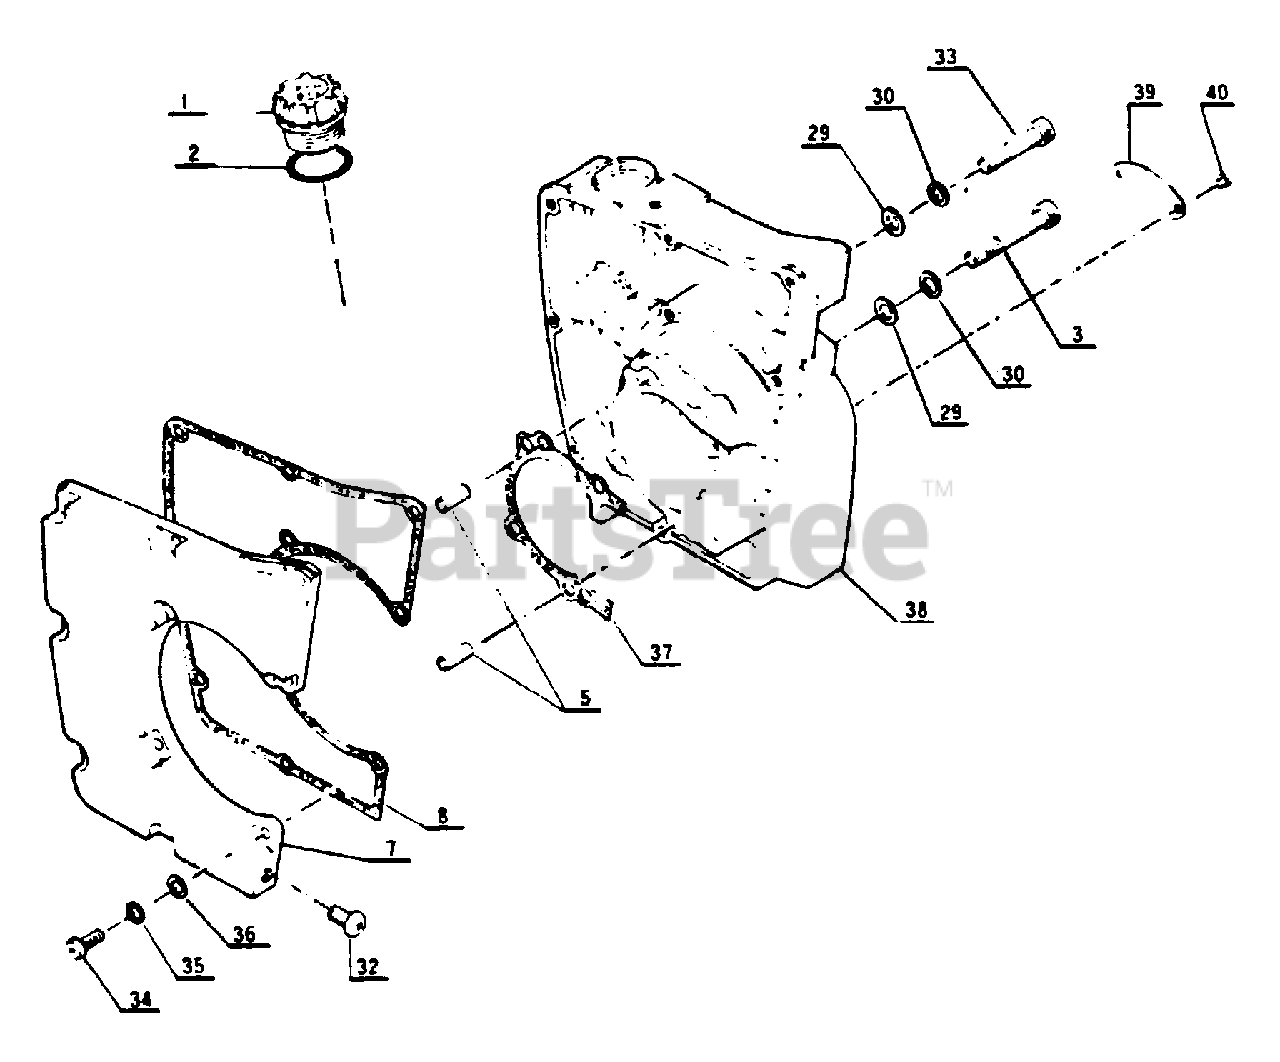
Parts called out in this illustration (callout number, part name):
1	CAP
2	GASKET, CAP
3	BOLT
5	PIN - LOCATING
7	TANK, OIL
8	GASKET
29	WASHER - 5
30	LOCKWASHER - 5
32	SCREW - 4X8
33	BOLT
34	SCREW - 4X12
35	LOCKWASHER - 4
36	WASHER - 4
37	GASKET, CRANKCASE
38	CRANKCASE
39	PLATE, MODEL
40	RIVET
